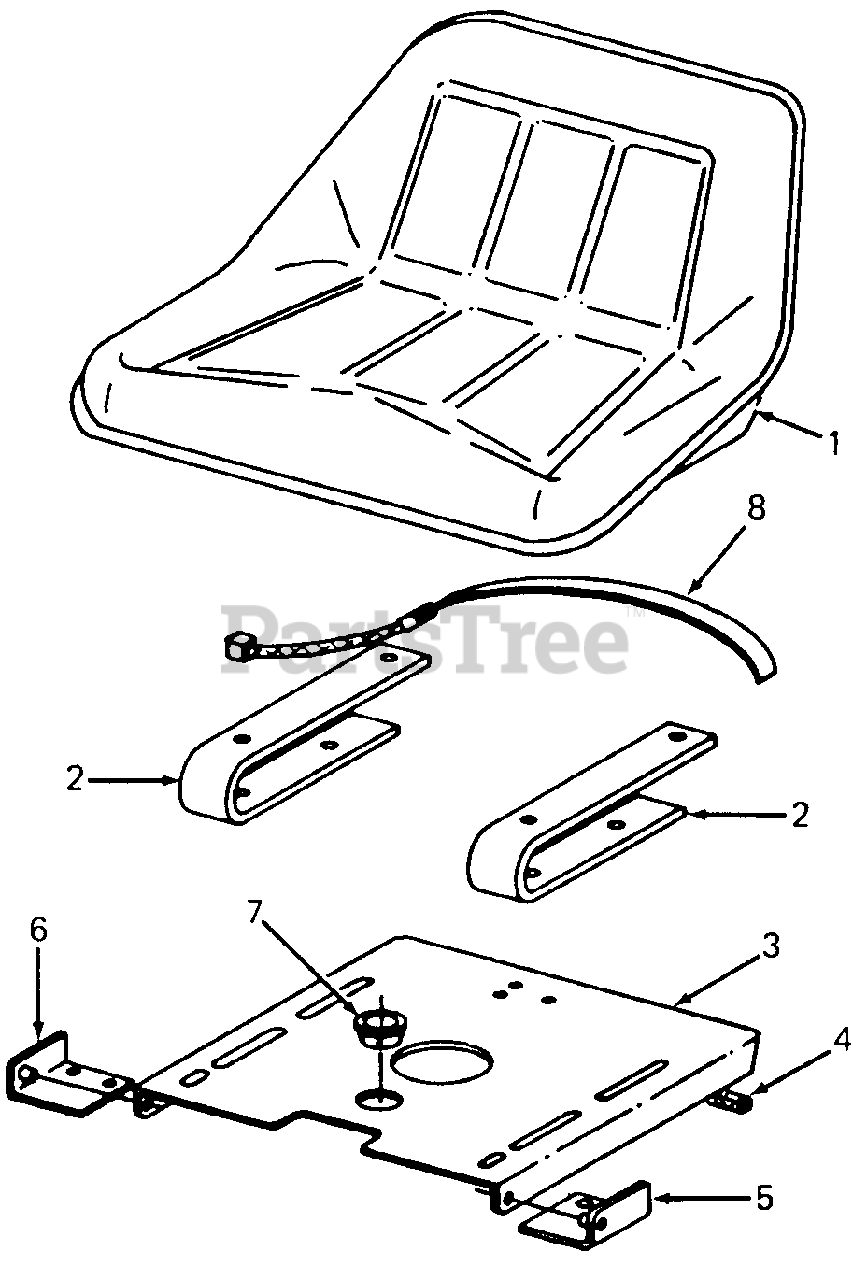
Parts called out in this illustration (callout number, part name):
1	Seat w/Graphic
2	Spring, Seat
7	Bushing, Snap, 1.0 ID
8	Switch Assy, Beam
